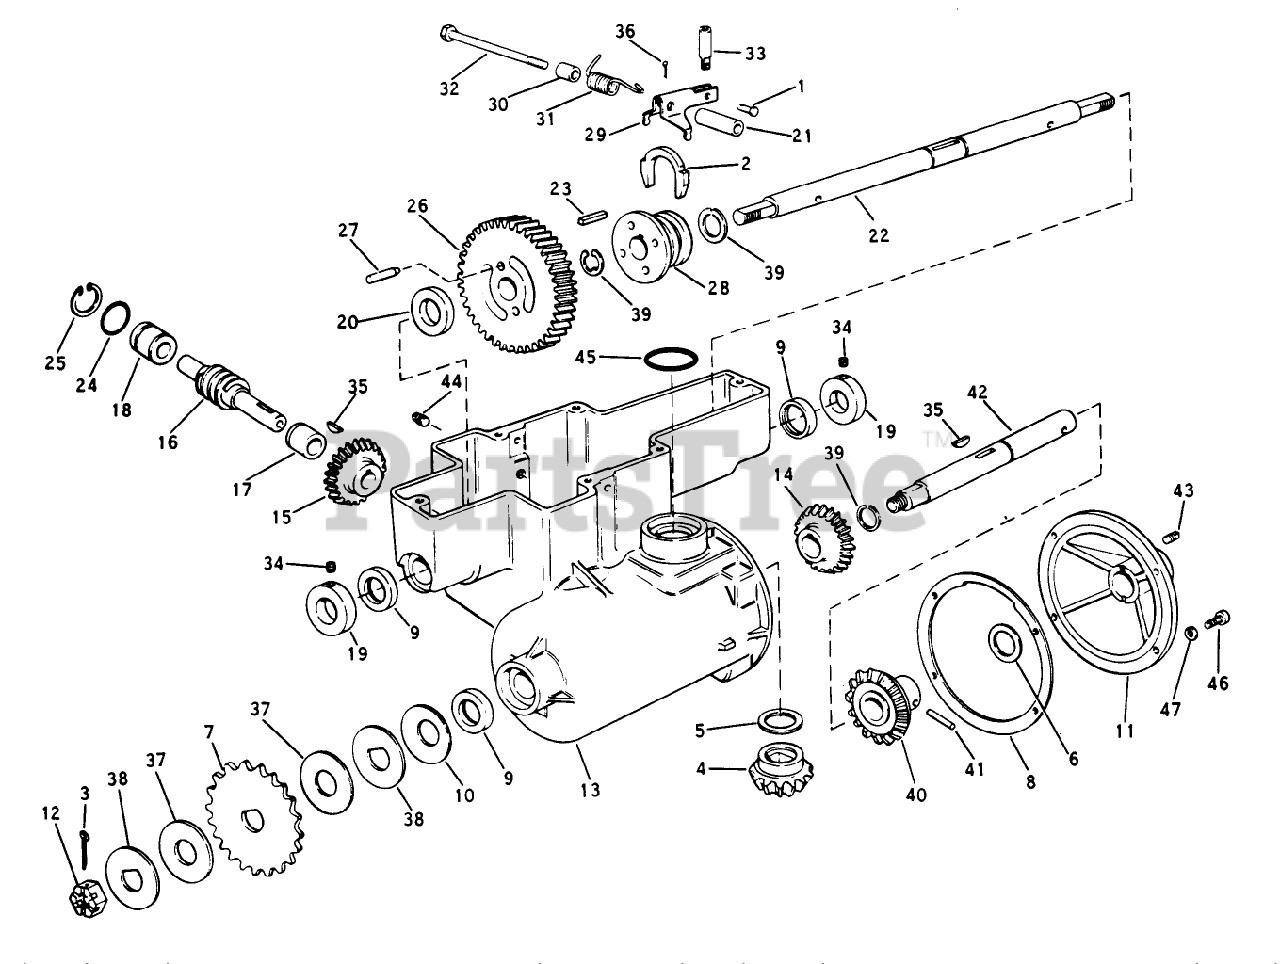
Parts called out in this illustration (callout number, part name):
3	Cotter Pin-Wheel
5	Thrust Washer-Pinion Gear
6	Thrust Washer-Driveshaft Gear
11	Cover-Gearcase
14	Pinion-Driveshaft
15	Gear-Worm Shaft
19	Collar-Axle
29	Lever-Drive Clutch
38	Washer-Steel
42	Driveshaft
43	Pipe Plug-Oil Fill-Gearcase
45	O Ring-G-case to Crankcase
46	Screw-Gearcase Cover
